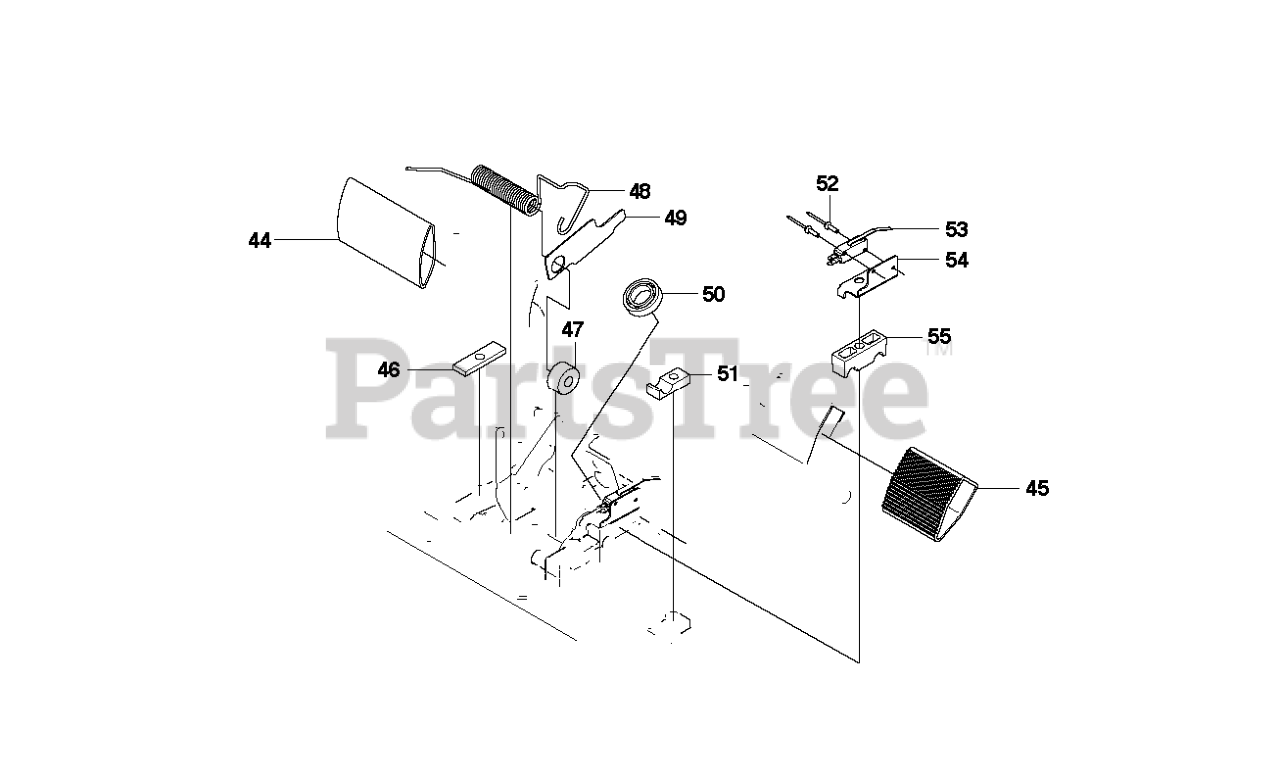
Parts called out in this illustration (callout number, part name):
44	PEDAL RUBBER, SF
45	PEDAL RUBBER
46	PLATE
47	ROLLER
48	SPRING
49	PLATE
50	BALL BEARING 6002-2RS1
51	SUPPORT
53	MICRO SWITCH
55	PEDAL SHAFT CLAMP
